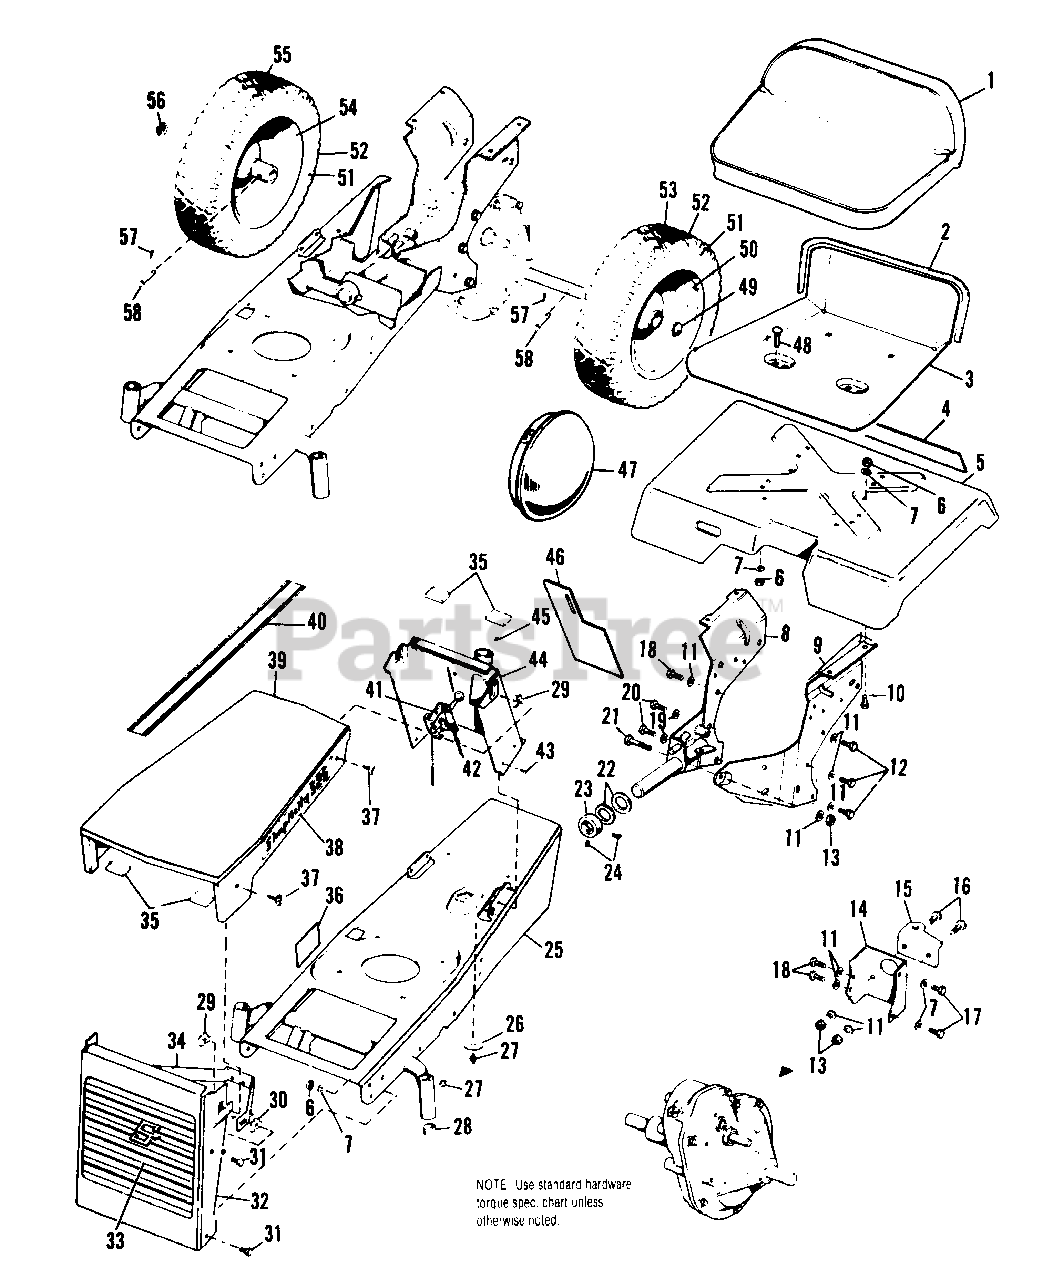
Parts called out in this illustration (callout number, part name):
1	PAD, Seat
3	PANEL, Seat
4	EMBLEM, Rear
5	SUPPORT, Seat (990485 Only)
5	SUPPORT, Seat
6	NUT, Hex, Full, 5/16-18
7	LOCKWASHER, 5/16
8	PLATE ASSY., Side (990485 Only)
9	PLATE, Side, L.H. (990485 Only)
9	PLATE, Side, L.H.
10	CAPSCREW, Hex Hd., 5/16-18 x 3/4
11	LOCKWASHER, 3/8
12	CAPSCREW, Hex Hd., 3/8-16 x 7/8
13	NUT, Hex, Full, 3/8-16
14	BRACKET, Draw Bar
15	CLIP, Draw Bar
16	CAPSCREW, Hex Hd., 3/8-16 x 1
17	CAPSCREW, Hex Hd., 5/16-18 x 1-1/4
18	CAPSCREW, Hex Hd., 3/8-16 x 3/4
19	LOCKWASHER, 7/16
20	CAPSCREW, Hex Hd., 7/16-14 x 3/4
21	CAPSCREW, Hex Hd., 3/8-16 x 1-3/4
23	COLLAR, Set
24	SETSCREW, 5/16-18 x 1/2
25	FRAME ASSY.
26	WASHER, Plain, #10
27	FITTING, Grease
29	NUT, Retainer
30	NUT, Speed
31	CAPSCREW, Hex Hd., 5/16-18 x 5/8
33	DECAL, Grille
34	SUPPORT, Grille
35	PAD, Felt
36	DECAL, Clutch
37	THUMB, Screw, 5/16-18 x 3/4
38	DECAL, Number (990485 Only)
38	DECAL, Number
40	STRIPE, Hood (990485 Only)
41	CONTROL, Choke (990485 Only)
41	CONTROL, Choke
42	CLIP, Speed (990485 Only)
43	SCREW, Hex, Taptite, 1/4-20 x 3/8
44	DASH ASSY.
45	SCREW, Self Tapping, 1/4-20 x 1/2
46	DECAL, Throttle (990485 Only)
46	DECAL, Throttle
47	CAP, Hub, Rear
48	BOLT, Carriage, 5/16-18 x 3/4
49	BUTTON, Plug
50	WHEEL ASSY., L.H.
53	WHEEL & TIRE ASSY., L.H.
54	WHEEL ASSY., R.H.
55	WHEEL & TIRE ASSY., R.H.
56	BUTTON, Plug
57	PIN, Cotter, 1/8 x 3/4
58	PIN
